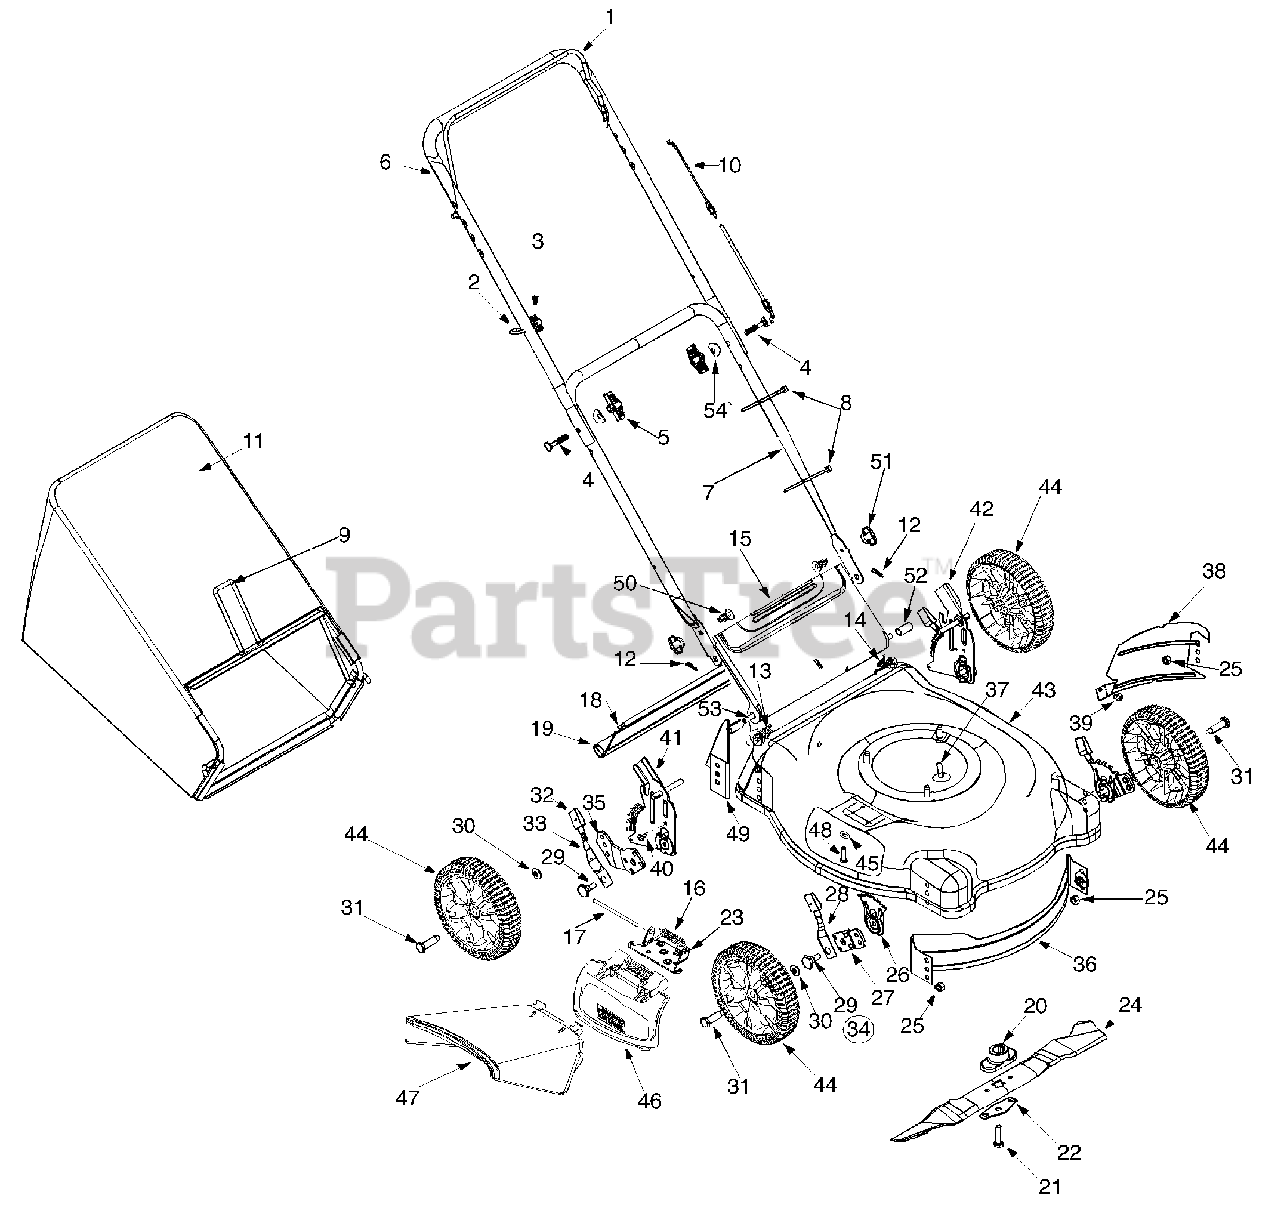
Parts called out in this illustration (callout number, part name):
2	Rope Guide
3	Handle Knob 1/4-20 Thd.
4	Curved Hd. Bolt 5/16-18 x 2"
5	Hand Knob
8	Cable Tie
10	Control Cable
11	Grass Bag
12	Int. Cotter Pin 5/16" Dia.
13	Door Spring - R.H.
14	Door Spring - L.H.
15	Rear Discharge Door
16	Torsion Spring
17	Hinge Pin
18	Wire Rod
19	Rear Flap
20	Blade Adapter w/Star
21	Hex Bolt 3/8-24 x 1.5" Lg.
22	Blade Bell Support
23	Deflector Chute Adapter
24	21" Mulching Blade w/Star
25	Flange Nut 3/8-16 Thd.
26	Height Adj. Plate
28	Front Spring Lever
29	Shld. Bolt.5" Dia. x.357"
30	Bell Washer.38" I.D. x.88" O.D.
31	Axle Bolt
32	Spring Lever Knob
33	Rear Spring Lever
34	Height Adj. Assy. Comp. - RH
35	Pivot Bar R.H.
39	Torx Mach AB-Tap Scr. 1/4 x.62"
40	Hex Ind Wash. Scr. 1/4-14:.625
45	Bell Washer 1/4" I.D.
46	Hinged Mulching Plug
47	Chute Deflector: Side Discharge
48	Hex Hd Self-Tp Scr. 1/4-20 x.5"
50	Hex Carriage Screw 1/4-20
51	Wing Nut
52	Spacer,.375OD x.50ID
53	Rear Door Pivot Rod
54	Shoulder Washer
